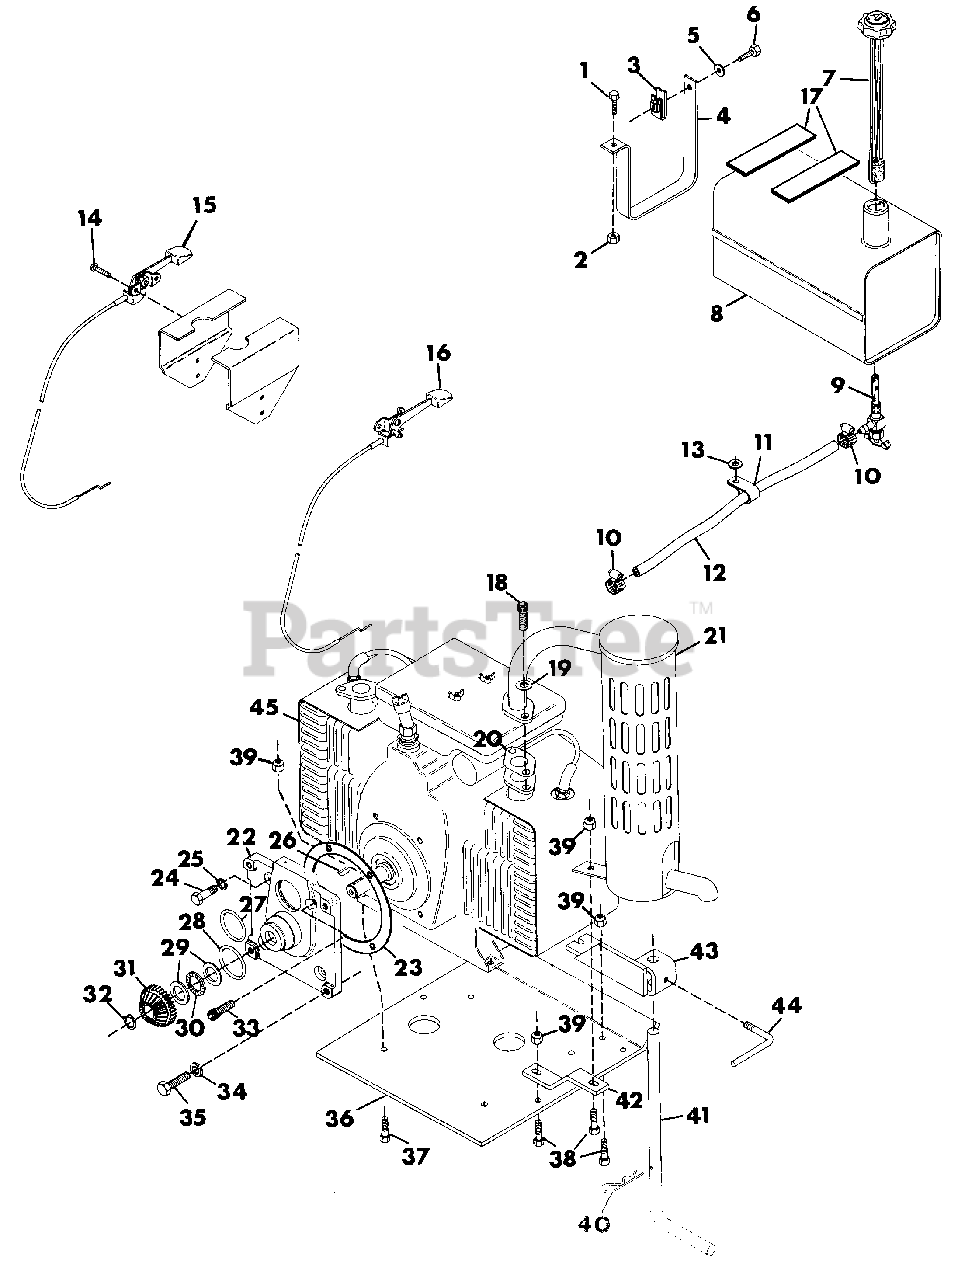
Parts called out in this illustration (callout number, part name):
1	BOLT, HEX 5/16-18X1.25
2	NUT, LOCK 5/16-18
3	NUT, RETAINER
4	STRAP, GAS TANK
5	WASHER,FLAT .312 X .734 X .065
6	BOLT, HEX 5/16-18X.75
7	GAUGE, FUEL
8	TANK, FUEL
9	VALVE AND STRAINER
10	CLAMP, FUEL HOSE
11	CLAMP, NYLON
12	LINE, FUEL
13	WASHER, FLAT .344X.688X.065
14	SCREW, TAPPING 10-24X.50 HHD SF
15	LEVER, CONTROL
16	LEVER, CONTROL
17	PAD, GAS TANK
18	SCREW, CAP 5/16-18X.75
19	WASHER, LOCK 5/16 REG.
20	GASKET, EXHAUST
21	MUFFLER, PRO MASTER-60 KT 17
22	ADAPTOR, ENGINE
23	GASKET, ENGINE
24	BOLT, HEX 7/16-14X1.125
25	WASHER, LOCK 7/16 SP HEAVY
26	KEY, SQUARE .250X1.250
27	O-RING, 2.50X2.750X.125
28	O-RING, 3.000X3.188X.094
29	RACE, BEARING THRUST
30	BEARING, THRUST
31	GEAR, SPUR AND BEVEL INPUT
32	RING, RETAINING 1.125 SHAFT
33	SCREW, CAP 7/16-14X1.00
34	WASHER, FLAT .531X1.062X.095
35	BOLT, HEX 1/2-13X1.25
36	PLATE, SKID
37	BOLT, HEX 3/8-16X1.25
38	BOLT, HEX 3/8-16X1.12
39	NUT, LOCK 3/8-16
40	PIN, HAIR
41	STAND, KICK
42	BRACKET, MUFFLER
43	STAND, SUPPORT
44	HANDLE, ADJUSTING
45	ENGINE, 17 HP KOHLER
45	ENGINE, 19 HP KOHLER
